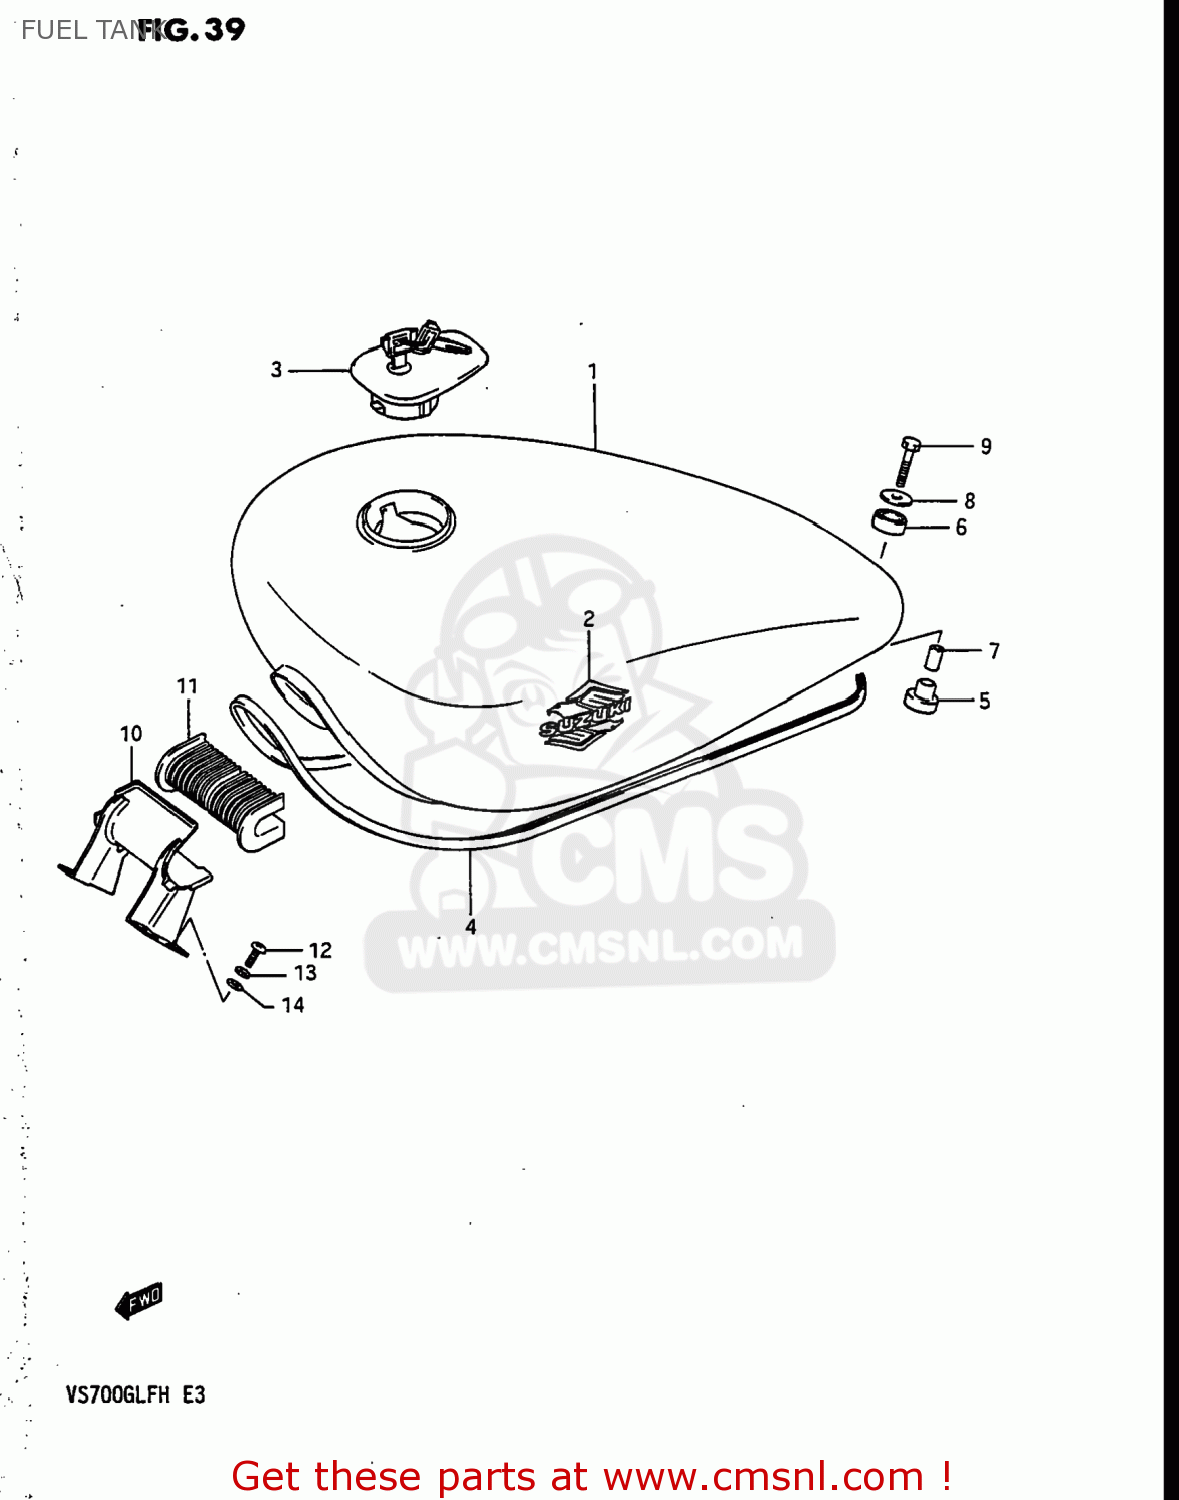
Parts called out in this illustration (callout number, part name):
1	TANK ASSEMBLY,FUEL
2	EMBLEM,FUEL TANK
3	CAP SET,FUEL TANK
4	MOLDING,FUEL TANK
5	CUSHION
6	CUSHION
7	SPACER (6.4X9X21.5)
8	WASHER (6.5X24X1.6)
9	SCREW
10	BRACKET COMP,FUEL TANK
11	CUSHION,FUEL TANK FR
12	SCREW
13	WASHER,LOCK
14	WASHER
